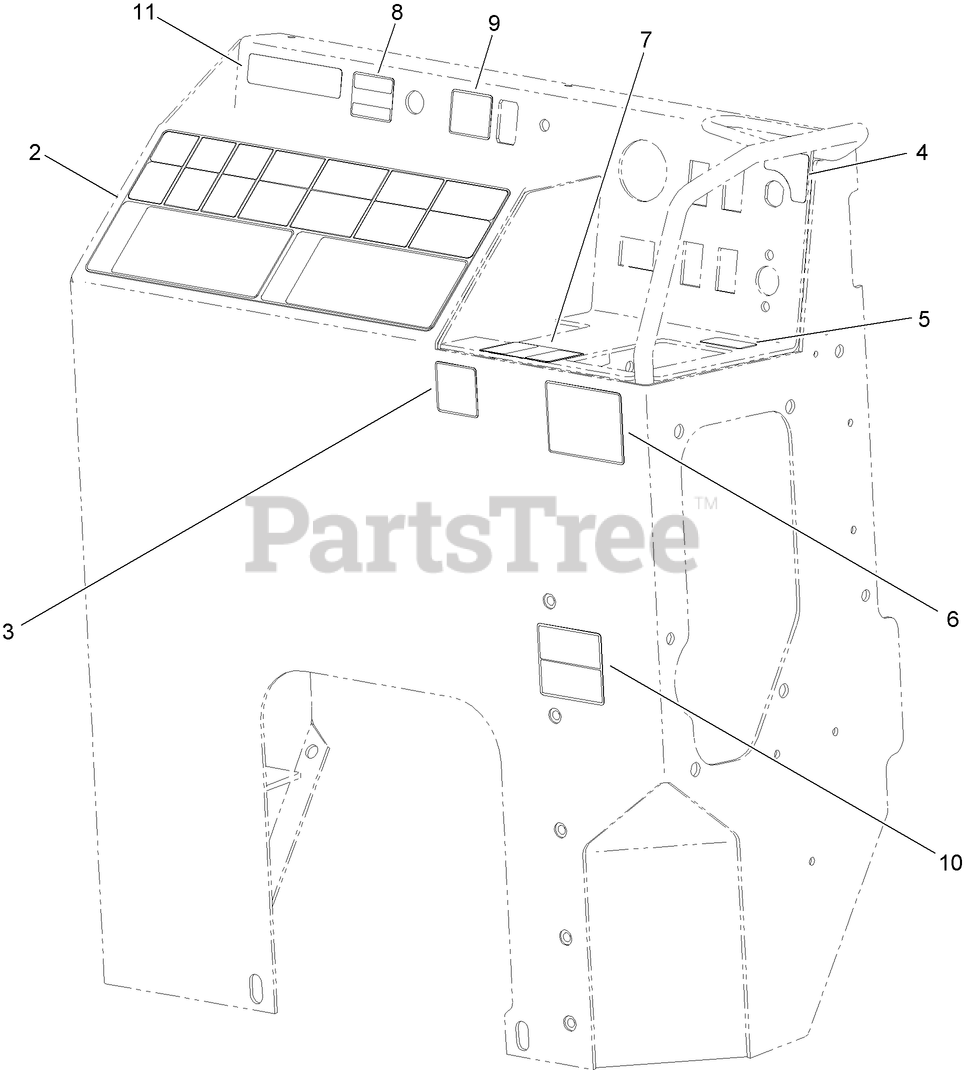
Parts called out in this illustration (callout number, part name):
2	DECAL-SAFETY
3	DECAL-PARKING BRAKE
4	DECAL-IGNITION
5	DECAL-GLOW PLUG
6	DECAL-GROUND DRIVE CONTROL
7	DECAL-ATTACHMENT LIFT
8	DECAL-THROTTLE
9	DECAL-PTO, VIBE PLOW
10	DECAL-WARNING, SHIELD
11	DECAL-ARRESTER, SPARK
